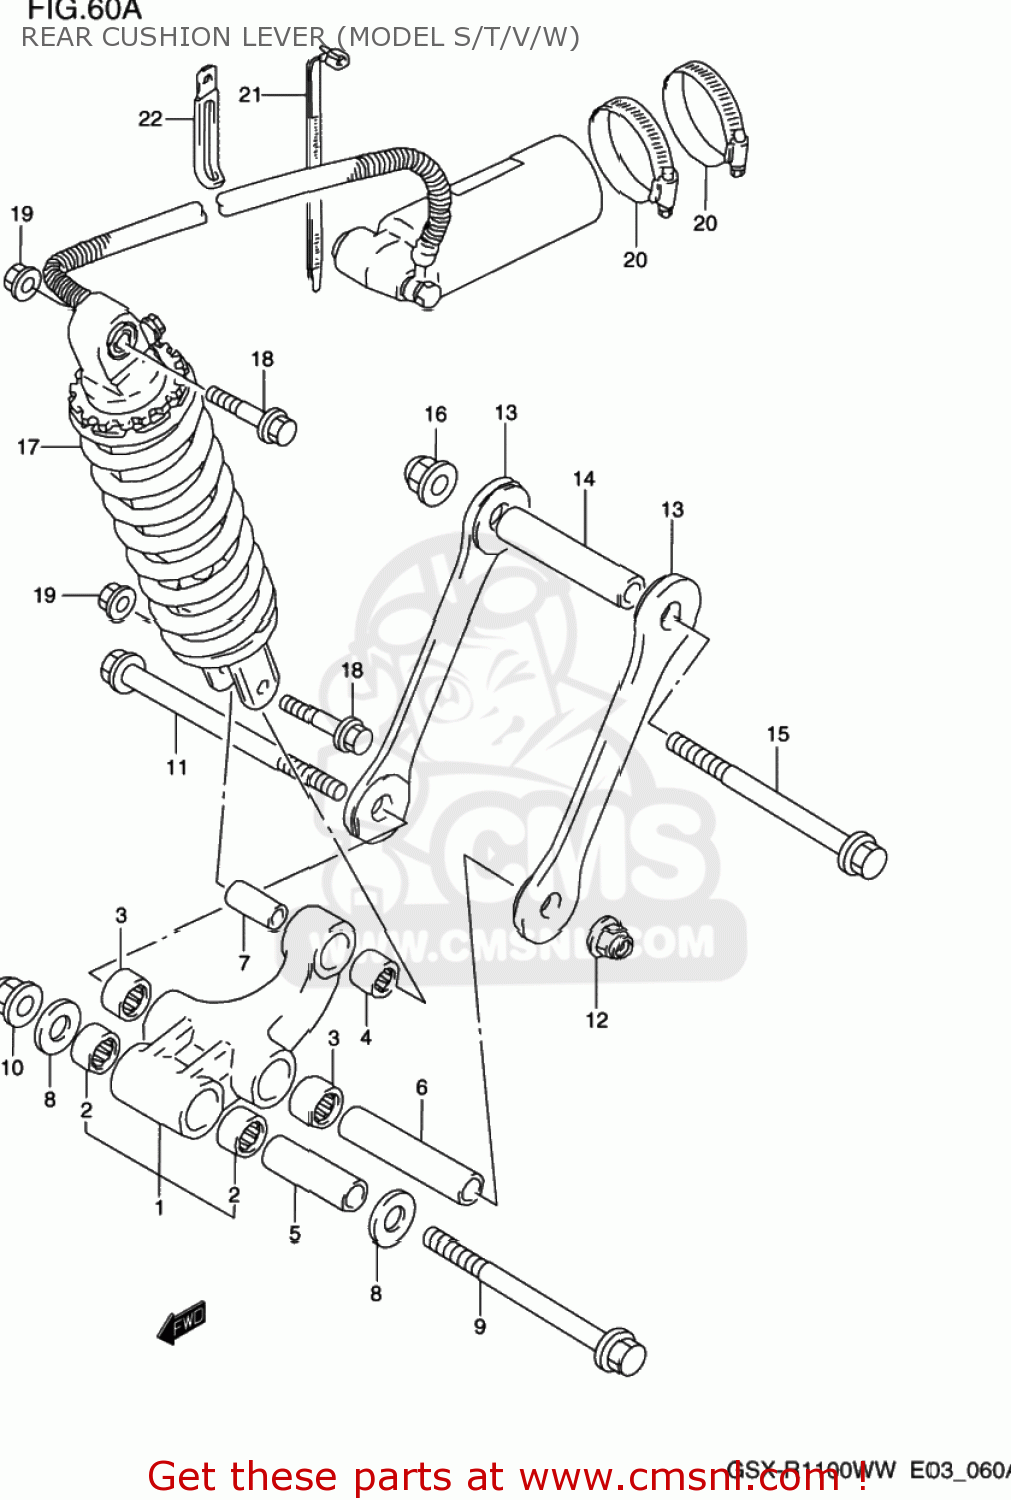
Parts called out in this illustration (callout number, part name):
1	LEVER SET,REAR CUSHION
2	BEARING(20X27X23.5)
3	BEARING(17X24X20)
4	BEARING(17X24X26)
5	SPACER,RR CUSHION LEVER
6	SPACER(12X17X85)
7	SPACER,RR CUSHION LEVER
8	WASHER
9	SHAFT,RR CUSHION LEVER FR
10	NUT
11	BOLT(12X115)
12	NUT 12MM
13	ROD COMP,REAR CUSHION
14	SPACER(12X17X85)
15	BOLT(12X115)
16	NUT 12MM
17	ABSORBER ASSY,RR SHOCK
18	BOLT(10X58)
19	NUT
20	CLAMP
21	CLAMP L:165
22	CLAMP(L:80)
